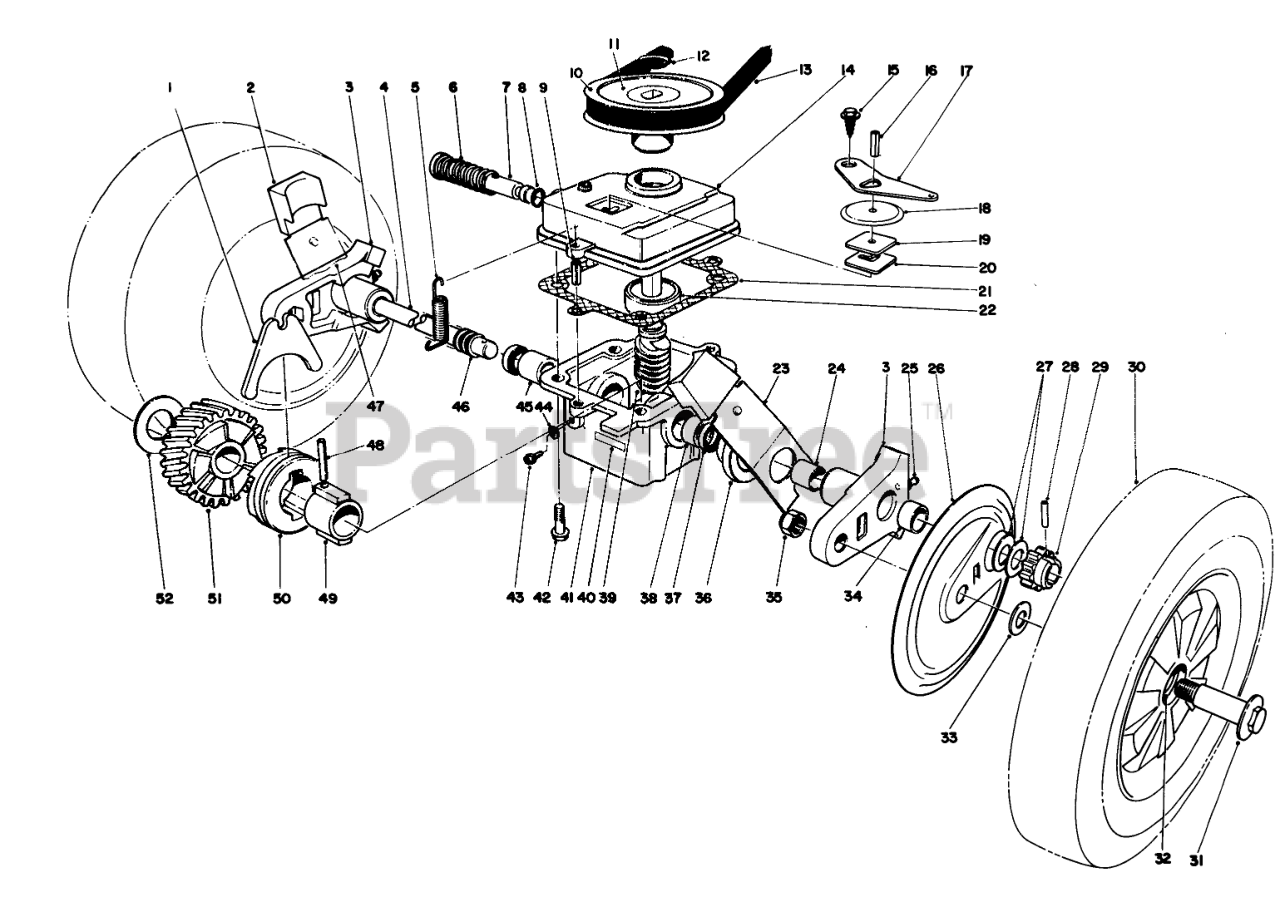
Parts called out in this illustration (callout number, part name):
1	SHIFTER FORK
2	KNOB-ARM
3	Pivot Arm (Incl. Ref. #24, 25 & 34)
4	DRIVE SHAFT (SERVCE)
5	TENSION SPRING
6	SPRING
7	SHIFTER ROD
8	O-RING
9	3/16 X 1/2 ROLL PIN
10	PULLEY
11	DECAL
12	PUSH-ON 93-3236
13	V BELT
14	GEAR CASE COVER
15	Screw
16	SPIROL PIN H D
17	SHIFTER ARM
18	DUST COVER
19	DUST FILTER
20	LATCH PLATE
21	GASKET
22	BEARING
23	SPRING ARM ASM SP LH
24	BUSHING
25	FITTING-GREASE
26	WHEEL COVER
27	THRUST WASHER
28	Pin
29	PINION GEAR 14T
30	Wheel & Tire Assembly (Incl. Ref. #32)
31	WHEEL BOLT
32	BUSHING
33	WASHER
34	BUSHING
35	Nut
36	CAP-END
37	SEAL-OIL
38	BUSHING
39	Worm Shaft & Gear (Incl. Ref. #51)
40	DECAL
41	Gear Case (Incl. Ref. #37-38 & 45)
42	Screw
43	NYLON SCREW
44	FILL PLUG GASKET
45	BUSHING
46	COVER-SHAFT, DRIVE
47	SPRING ARM ASM SP RH
48	COIL PIN
49	SLEEVE
50	CLUTCH JAW
51	Helical Gear
52	THRUST WASHER
